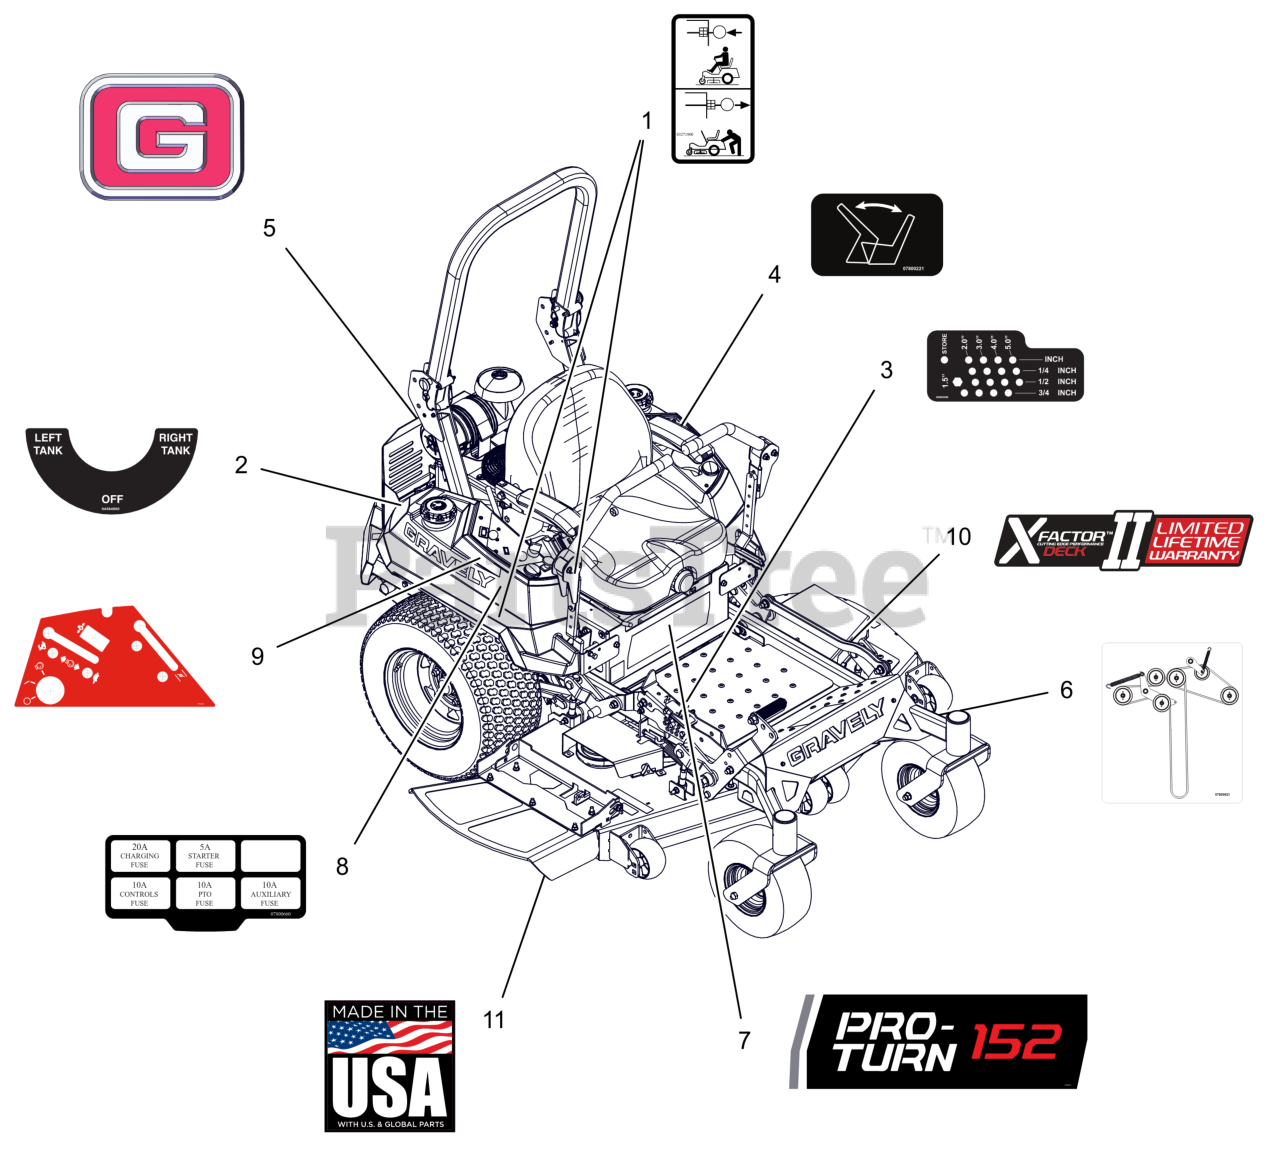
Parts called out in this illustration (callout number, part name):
1	DECAL, TRANSMISSION DISCONNECT
2	DECAL, FUEL VALVE
3	DECAL, HEIGHT OF CUT
4	DECAL - SEAT RELEASE
5	DECAL, GRAVELY BRAND
6	DCL,BELT ROUTE-RH V-SIDE IDLER
7	DECAL, PRO-TURN 152
8	DECAL, FUSE BLOCK
9	DECAL, NON-EFI CONTROL PANEL
10	DECAL, X-FACTOR DECK
11	DECAL, MADE IN USA
